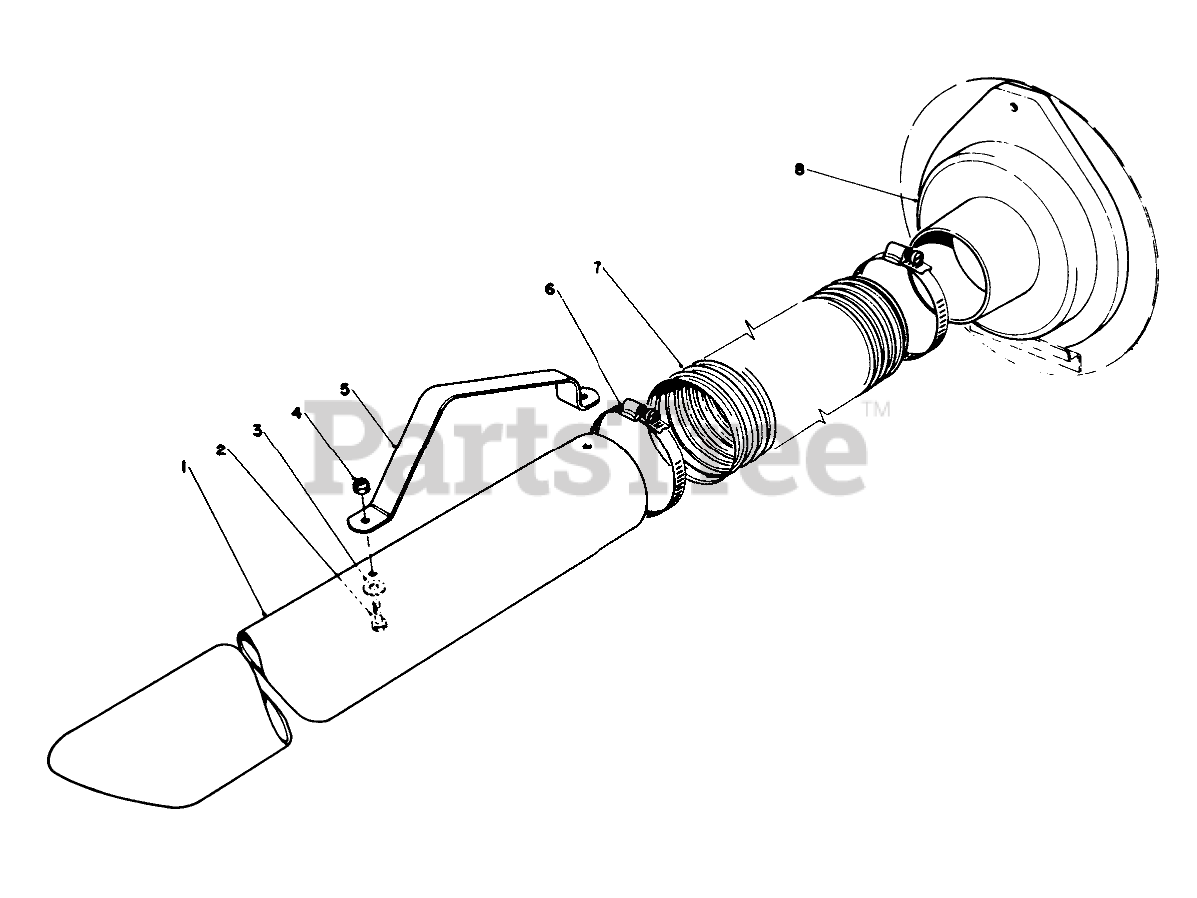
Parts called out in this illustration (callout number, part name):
1	NOZZLE
2	SCREW-HH
3	SPECIAL WASHER
4	NUT-KEPS
5	NOZZLE HANDLE
6	CLAMP
7	VACUUM HOSE
8	ADAPTOR HOSE TO HSG
